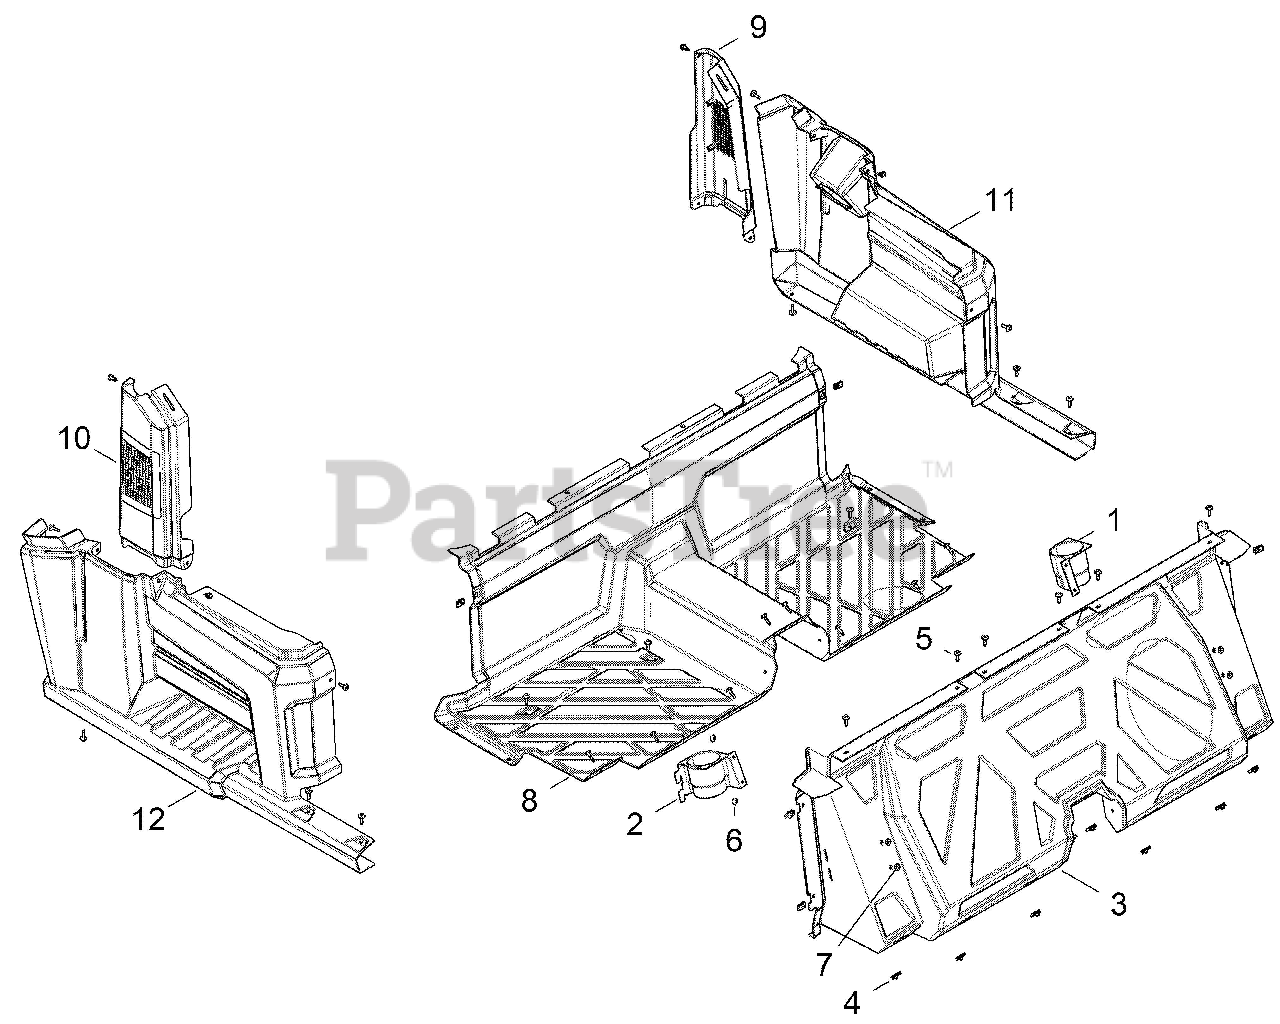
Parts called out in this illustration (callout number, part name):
1	HOLDER, CUP, LH, BLACK
2	HOLDER, CUP, RH,BLK
3	FLOOR,PANEL,REAR,BLK
4	CLIP-U SPEED NUT
5	SCR-TXTH-M6X1.0X25 RIE
6	RIVET-MALE.625X.32-.34,BLK
7	RIVET-TUFLOK,.315-.325X.787 (5
8	FLOOR,REAR,BLK
9	ASM-FENDER-REAR,UPPER,LH,BLK
10	ASM-FENDER-REAR,UPPER,RH,BLK
11	FENDER,REAR,W/ROCKER,CREW, LH
12	FENDER,REAR,W/ROCKER,CREW,RH
